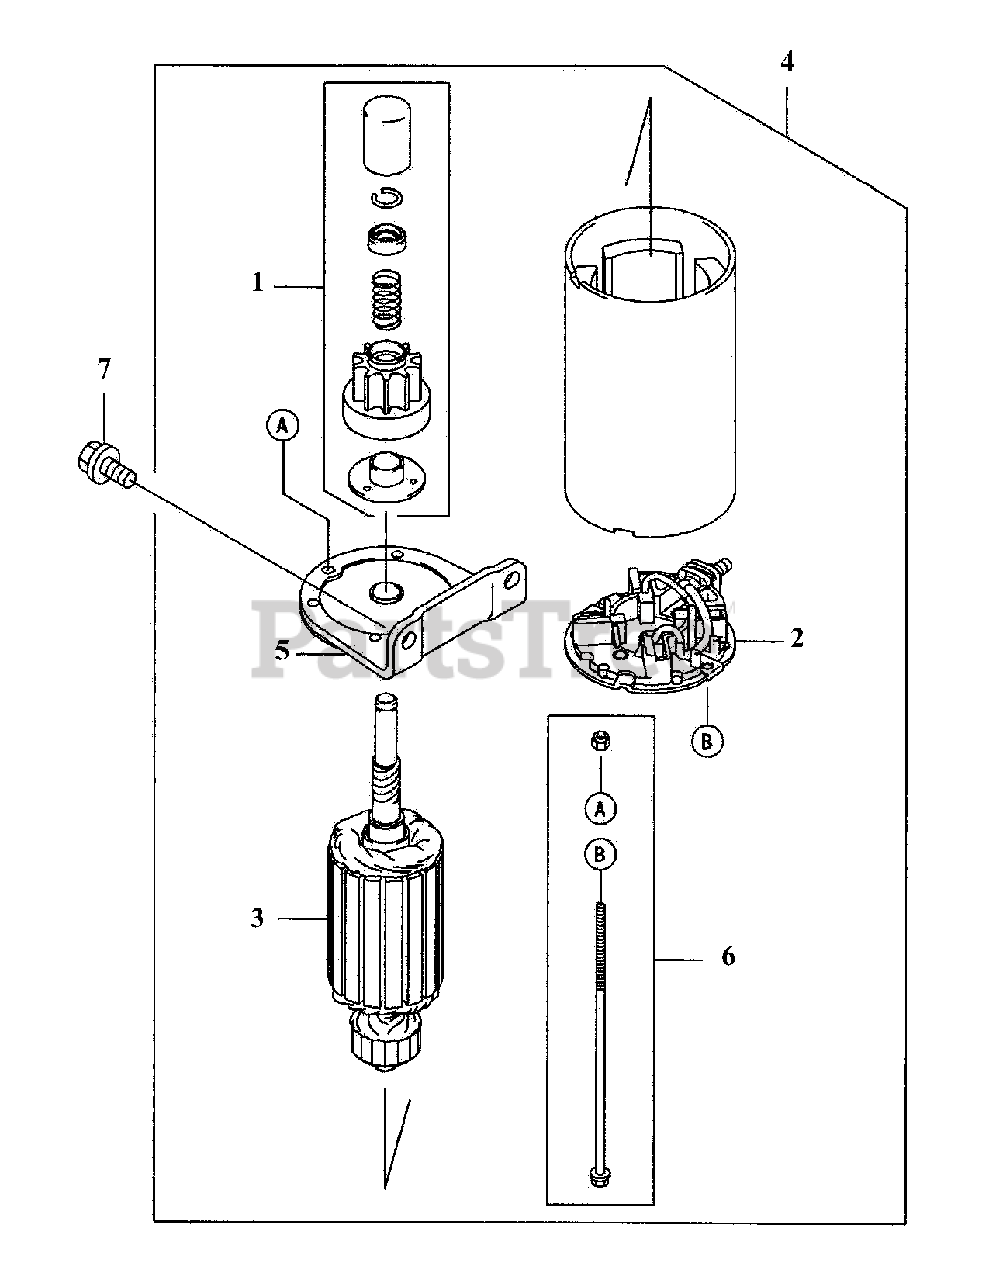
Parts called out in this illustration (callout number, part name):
1	Gear Assembly
4	Starter, Electric
5	Bracket, Assembly
7	Bolt, Flanged
